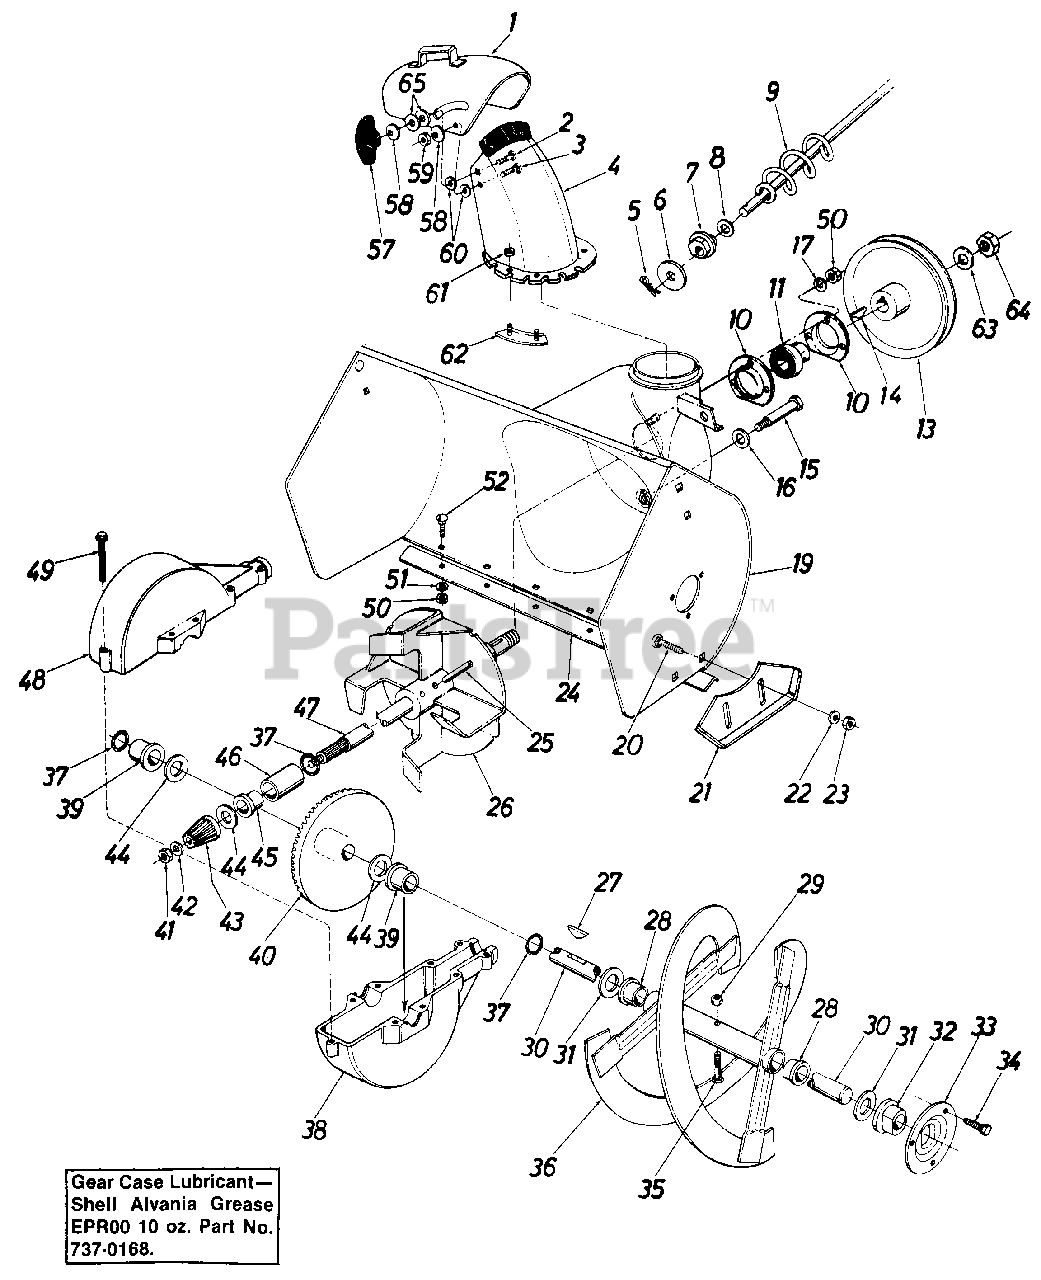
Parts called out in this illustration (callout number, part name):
1	Top Chute Ass'y.
2	Carriage Bolt 5/16-18 x 1.00" Lg.
3	Carriage Bolt 5/16-18 x .62" Lg.
4	Chute Ass'y.
5	Cotter Pin
6	Fl-Wash. .390 I.D. x 1.50" O.D.
7	Hex Bushing
8	Fl-Wash. .385 I.D. x .62" O.D.
9	Chute Crank Ass'y.
10	Bearing Housing
11	Self-Align Brg. w/Collar .75" I.D.
13	1/2" "V"-Pulley .625" I.D. x 7.50" O.D.
14	#61 Hi-Pro Key 3/16" x 5/8" Dia.
15	Shld. Bolt .50" Dia. x 2.11" Lg.
16	Bell-Wash. .40" I.D. x .88" O.D. x .06
17	L-Wash. 5/16" I.D.
19	Blower Housing Ass'y.
20	Carriage Bolt 3/8-16 x .62" Lg.
21	Slide Shoe
22	Bell-Wash. 3/8" I.D.
23	Hex Jam Nut 3/8-16 Thd.
24	Shave Plate - 24" Lg.
25	Spring Pin Spiral 1/4" Dia. x 1.50" Lg.
26	11" Dia. Blower Fan Ass'y.
27	#9 Hi-Pro Key 3/16 x 3/4" Dia.
28	Flange Brg. .75" I.D. x .88" O.D. x .62
29	Hex Ins. L-Nut 5/16-18
30	Spiral Axle
31	Fl-Wash. .75" I.D. x 1.50" O.D. x .06
32	Flange Brg. w/Flats .755" I.D.
33	Bearing Housing
34	Hex Wash. Hd. Self-Tap Scr. 5/16-24 x .50" Lg.
35	Hex Bolt 5/16-18 x 1.50" Lg.
36	Spiral Ass'y. - L.H.
37	"O"-Ring - 3/4" I.D.
38	Bevel Gear Housing - Lower Half
39	Plastic Flange Brg. .755" I.D.
40	Bevel Gear
41	Hex Cent. L-Nut 5/16-24 Thd.
42	Fl-Wash. .34" 1.D. x .62" O.D. x 06
43	Pinion Gear
44	Fl-Wash. .75" I.D. x 1.25" O.D. x .06
45	Flange Brg. .755" I.D.
46	Sleeve Brg. .755" I.D.
47	Blower Axle
48	Bevel Gear Housing - Upper Half
49	Hex Wash. Hd. Self-Tap Scr. 1/4-20 x 1.00" Lg.
50	Hex Nut 5/16-18 Thd.
51	Bell-Wash. .34" I.D. x .88" O.D.
52	Carriage Bolt 5/16-18 x .62" Lg.
57	Knob
58	Bell-Wash. .34" I.D. x .88" O.D.
59	Hex Cent. L-Nut 5/16-18 Thd.
60	Fl-Wash. .53" I.D. x 1.25" O.D. x .100
61	Hex Cent. L-Nut 1/4-20 Thd.
62	Chute Flange Keeper Ass'y.
63	Fl-Wash. .64" I.D. x .94" O.D. x .06
64	Hex Jam Nut 5/8-18 Thd.
65	Fl-Wash. .344 I.D. x 1.125 O.D.
